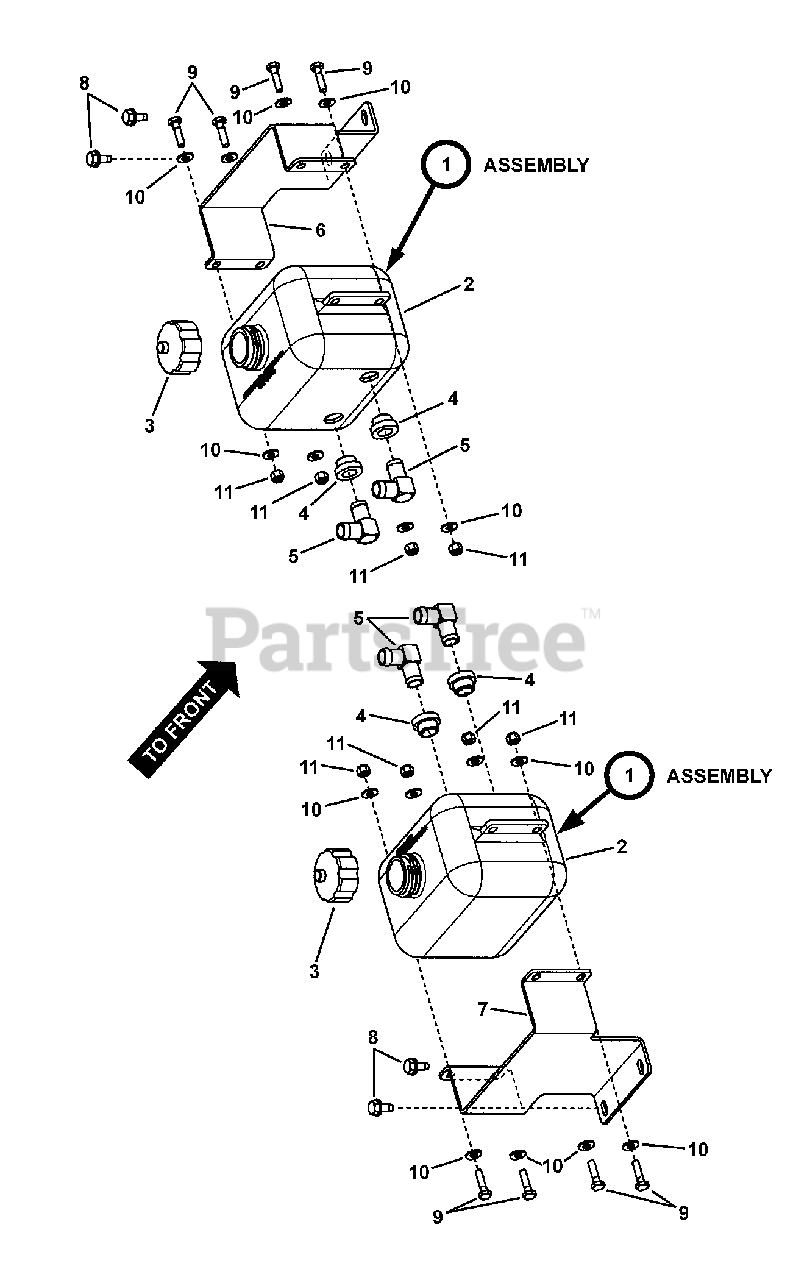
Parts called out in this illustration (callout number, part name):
1	ASSY, Hydraulic Tank (Includes 4 items shown below)
2	TANK, Hydraulic, NZM
3	CAP, Vented (Kelch # H4550D)
4	GROMMET (Dapco # 12078)
5	ELBOW FITTING (Dapco # 12183)
6	BRACKET, R.H. Hydro Tank Mount
7	BRACKET, L.H. Hydro Tank Mount
8	SCREW, 1/4-20 x 1" Hex Head Cap GR 5
9	WASHER, 1/4" Flat
10	SCREW, 5/16-18 x 5/8" Hex Washer Self-Tap
11	NUT, 1/4-20 HEX NYLON LOCK
